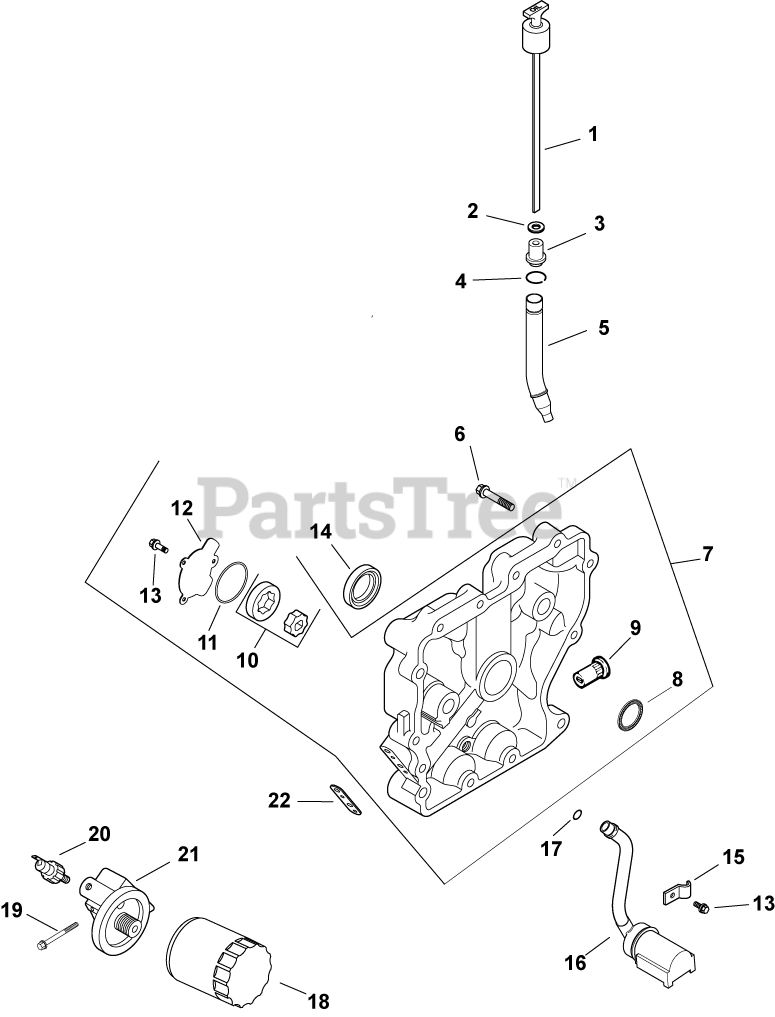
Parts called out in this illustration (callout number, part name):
3	SEAL USE 25 032 13-S
5	TUBE, OIL FILL
6	SCREW, FLG M8X1.25X45
7	CLOSURE PLATE ASSEMBLY
8	BEARING, CRANKSHAFT
9	VALVE, OIL PRESSURE RELIEF
10	PUMP ASSEMBLY, OIL
11	O-RING (1.78" DIA)
12	COVER, OIL PUMP
13	SCREW,FLG THD FRM M5X0.8X16-(#25086398S)
14	SEAL, OIL
16	KIT, OIL PICK-UP
17	O-RING (.5" DIA)
18	OIL FILTER
19	SCREW, FLG M6X1.0X60
20	SENSOR, OIL PSI
21	ADAPTER - DISCONTINUED
22	GASKET, OIL FILTER ADAPTER
